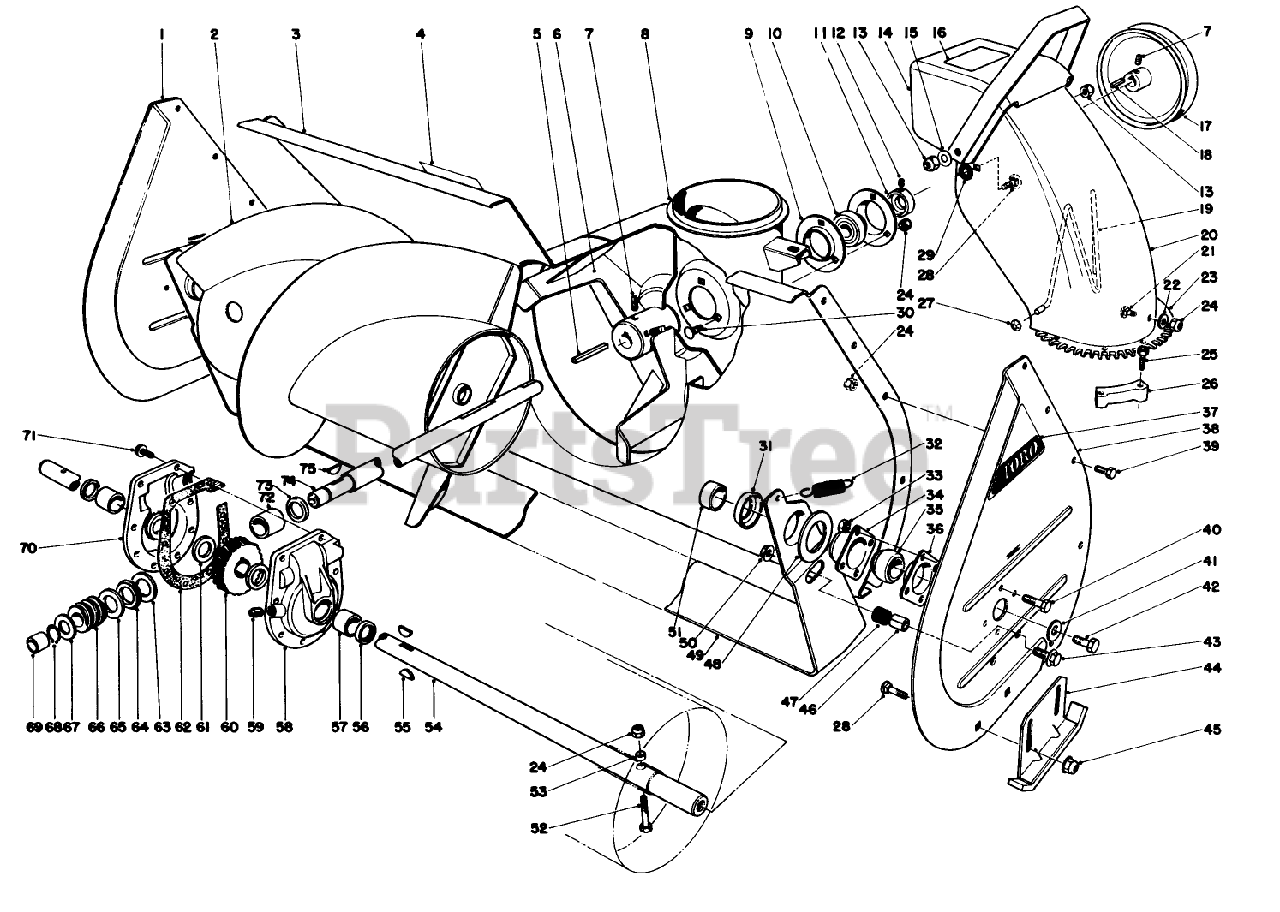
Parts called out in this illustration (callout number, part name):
2	RH AUGER ASM - 32"
3	AUGER HSG WA 32" *R
7	SCREW-SET, SQH
8	CHUTE RING
9	BRG FLANGE
10	BALL BRG W/COLLAR
11	EXT LOCKING COLLAR
12	SCREW-HSH
13	NUT-LOCK, CONE
15	WASHER-BELLEVILLE
18	SQUARE KEY
19	WIRE-CHUTE
21	SCREW-CARR
22	WASHER-PLAIN
24	NUT-LOCK, CONE
25	SCREW-SPECIAL
26	RETAINER-CHUTE
27	NUT-PUSH
28	SCREW-CARR
29	Rubber Washer
30	BOLT-CARR
32	SPRING-TENSION
34	BEARING-FLANGE, FRONT
35	BEARING
36	BEARING-FLANGE, REAR
39	SCREW-HH
40	SCREW-HH
41	WASHER
42	SCREW-HH
43	SCREW-HHF
45	NUT-HHF, WHIZ
47	SCRAPER STOP CUSHION
48	SCRAPER BLADE SPACER
49	SCRAPER BLADE 32" *R
50	NUT-HF
53	SPACER-HUB, AUGER
55	KEY-WOODRUFF
56	SEAL-OIL
57	BUSHING
59	PLUG-PIPE, SQH
60	GEAR-WORM, 27T
61	WASHER-THRUST
63	WASHER-THRUST
64	BEARING-THRUST
65	THRUST-WASHER
67	WASHER-THRUST
68	RING-SNAP
69	BUSHING
71	SCREW-THD ROLL, HWH
72	BUSHING-SPECIAL
73	RING-QUAD
74	SHAFT-IMPELLER
75	KEY-WOODRUFF
